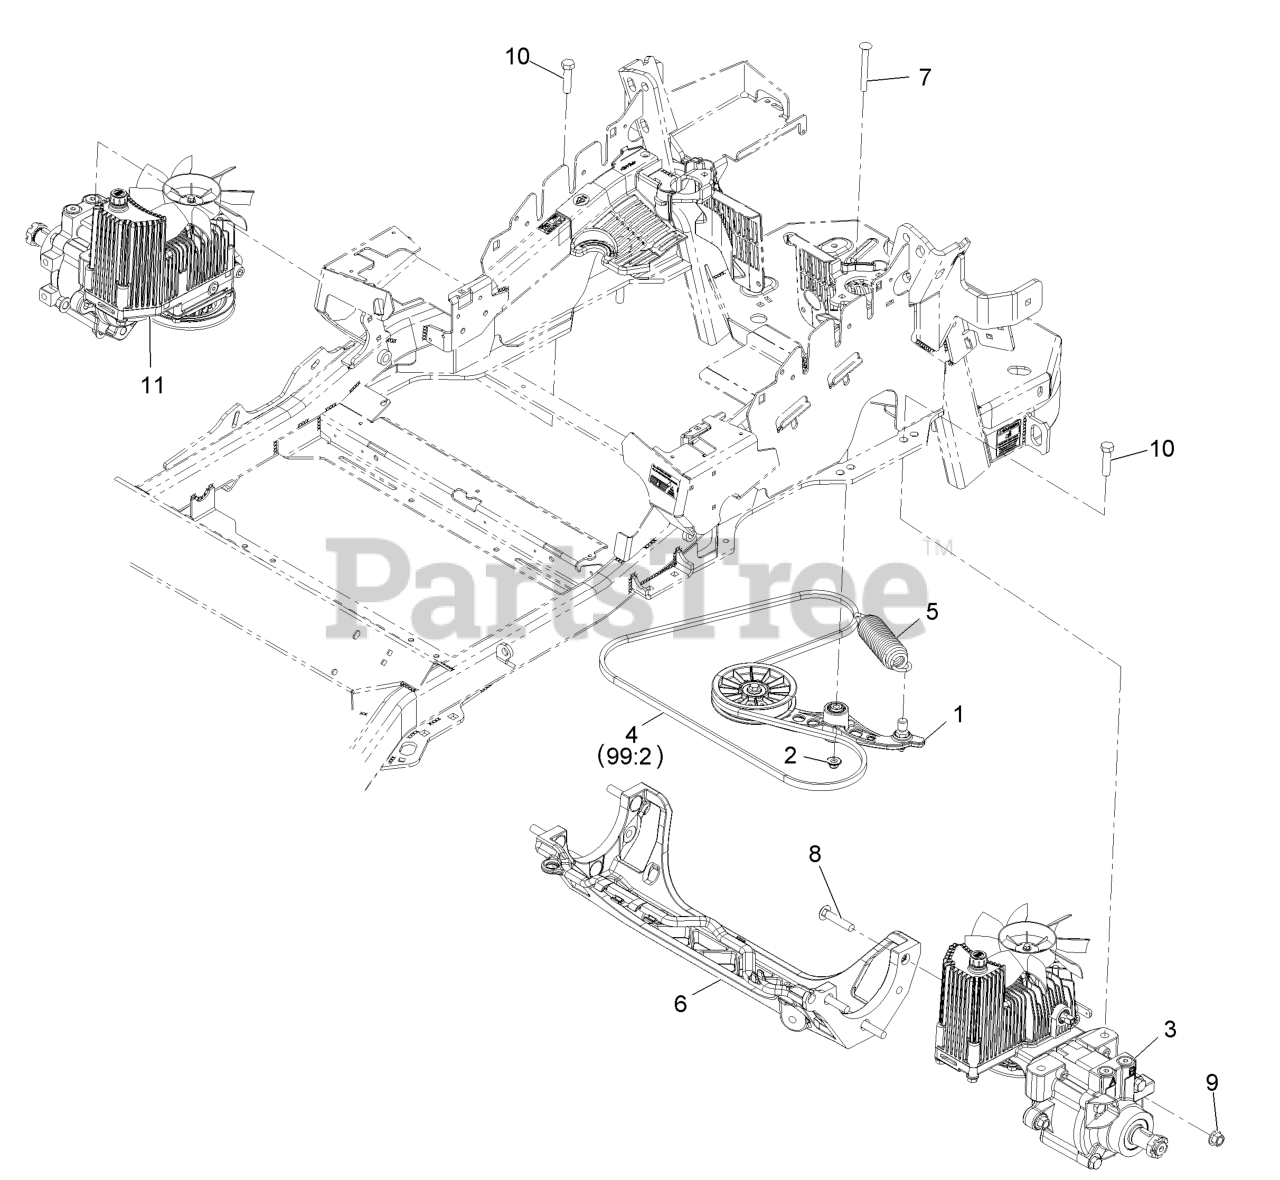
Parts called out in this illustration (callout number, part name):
1	PUMP IDLER ASM
2	Nut-Nyloc 3/8-16 Flg
4	BELT
7	BOLT-SHOULDER, CARRIAGE 3/8-16 X 3 1/2
8	SCREW-CARR
9	Nut-Lock 1/2-13
10	SCREW-HH
99:2	BELT
